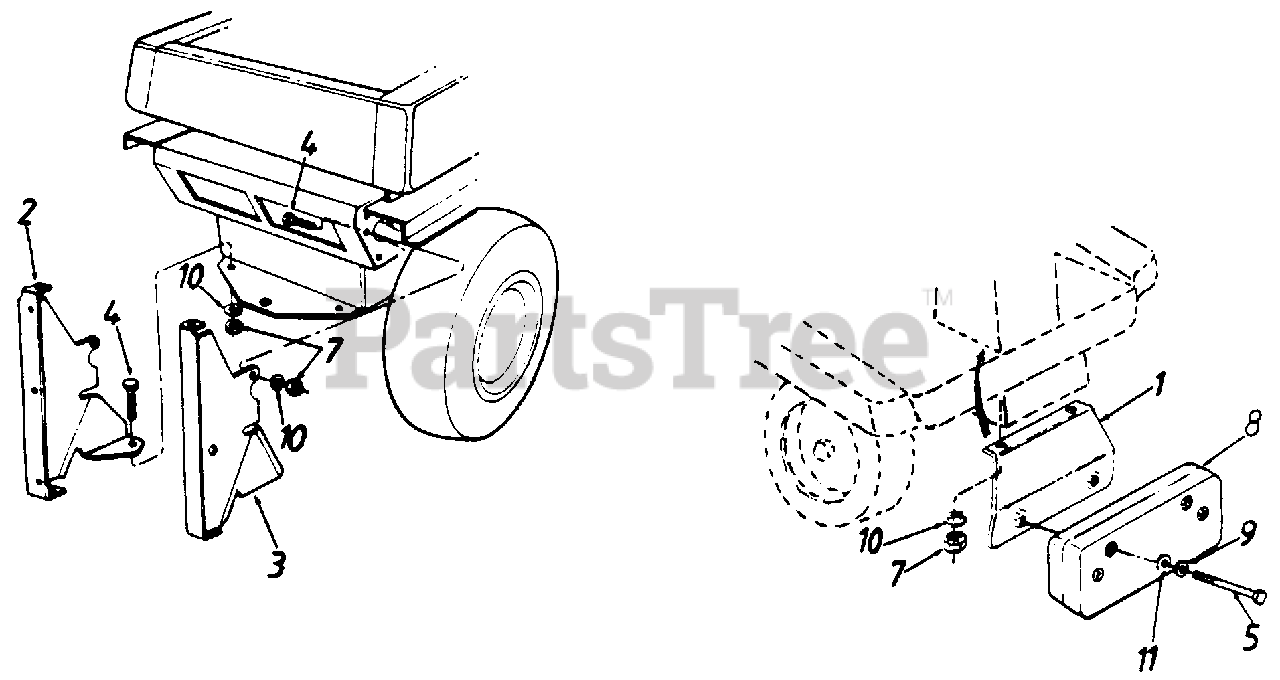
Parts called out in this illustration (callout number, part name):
1	Counterweight Support Brkt. 1
2	Catcher support Brkt.-R.H. 1
3	Catchor support Brkt.-L.H. 1
4	Hex Bolt 5/16-18 x 1.0" Lg. 4
5	Hex Bolt 3/8-16 x 4.5" Lg. 2
7	Hex Nut 5/1-18 Thd.- 0 6
8	Front Counterweight
9	Bell-Wash. 3/8 I.D. 2
10	L-Wash. 5/16 I.D.- 0 6
11	Fl-Wash. .390" l.D. x 1.12 O.D. 2
